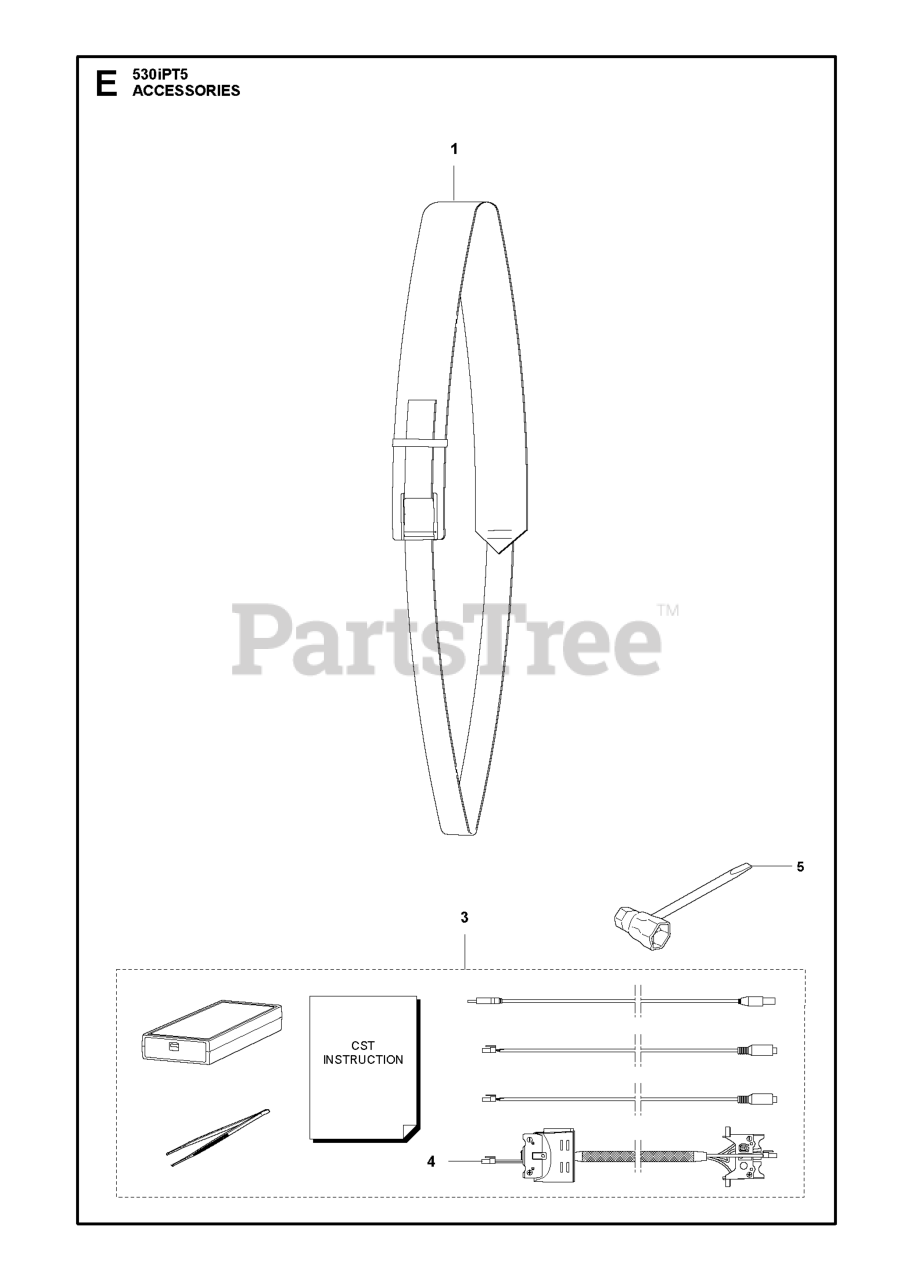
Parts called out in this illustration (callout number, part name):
1	HARNESS WITHOUT HOOK
3	DIAGNOSTIC TOOL KIT
4	WIRING ASSY
5	COMBI TOOL
